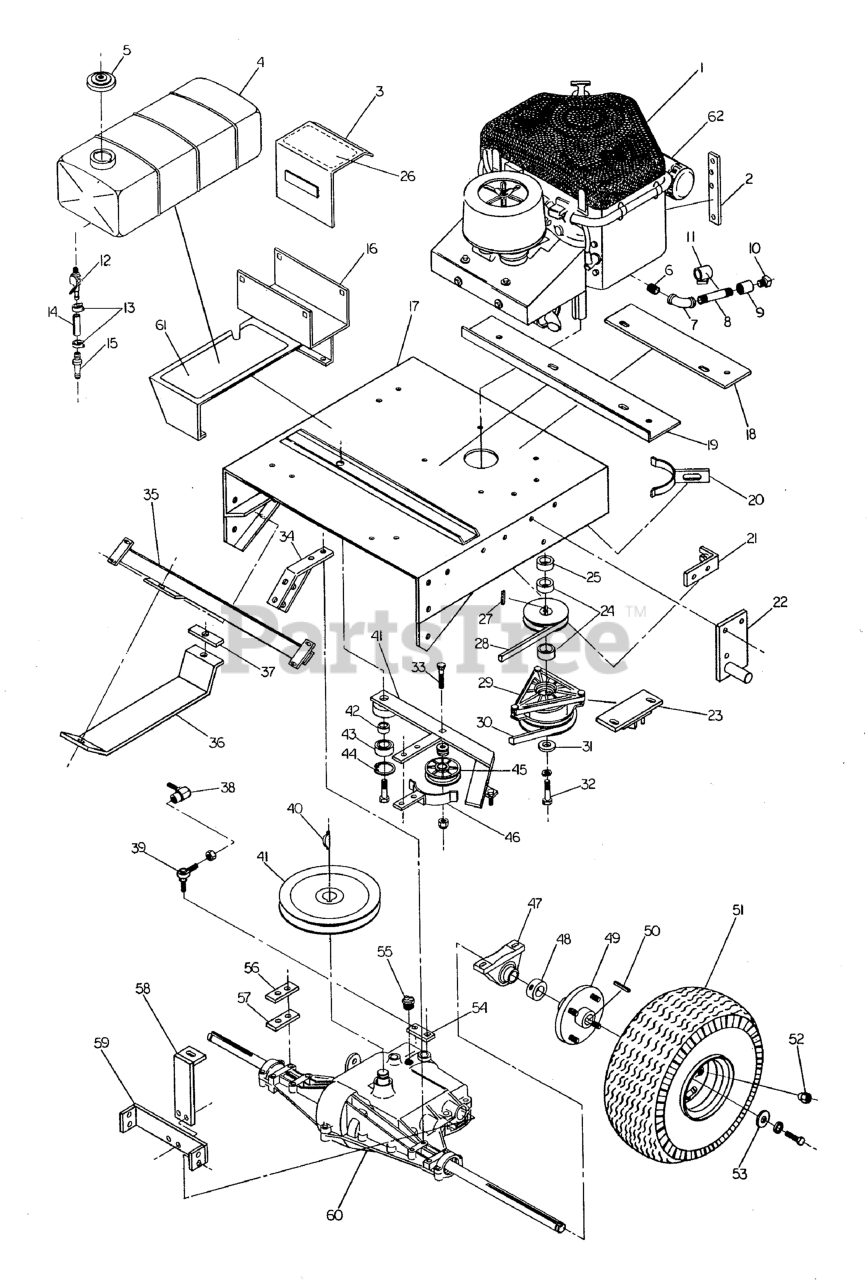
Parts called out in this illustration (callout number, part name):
2	Oil Filter Mount
3	Battery Cover
4	Fuel Tank, 4 Gallon
4	Gas Tank Strap
5	Gas Cap
6	Close Nipple
7	Elbow 45 Degree
8	Pipe Nipple
9	Coupler
10	Pipe Plug
11	Oil Drain Hold Down
12	Fuel Shut-Off Valve
13	CLAMP, Hose
14	Fuel Line
15	FUEL FILTER
16	Gas Tank Mount
17	Engine Deck
18	Rear Engine Deck Support
19	Front Engine Deck Support
20	Engine Belt Guide
21	Clutch Cable Bracket
22	Pivot Bracket - LH
22	Pivot Bracket - RH
23	Electric Clutch Anchor
24	SPACER, 1.01 x 1.50 x .37
25	Transaxle Pulley
26	SAFETY WALK
27	KEY, 1/4" SQ. X 1-1/4
28	Belt Ground Drive
29	CLUTCH, Electric, 1" Shaft
30	BELT, B-Section
30	Belt 48" Deck
31	SPACER, .45 x 1.62 x .37
34	Torque Arm
35	Engine Deck Cross Member
36	Skid Plate
37	Skid Plate Spacer
38	BALL JOINT, 3/8" Female Studded
39	BALL JOINT, 3/8-24 Male, Studded
40	Hy Pro Key
41	Ground Drive Pulley
42	INSERT, Bearing Shoulder
43	BEARING, BALL 11/16X1-9/16X15/32
44	SNAP RING, Internal
45	Idler Pulley
46	Belt Guide
47	BEARING, PILLOW BLOCK, 1
48	COLLAR, 1" Split
49	4-Bolt Hub
50	KEY, 1/4 SQ. X 2-1/2
51	WHEEL & TIRE ASSEMBLY, 20 x 10 x 8, Complete
51	TIRE & WHEEL ASSEMBLY, 18 X 8.5 X 8
52	LUG NUT, 1/2-20
53	Retaining Spacer
54	Shifting Lever
55	Neutral Safety Switch
56	3/16 Transmission Spacer
57	1/4 Transmission Spacer
58	Transmission Support Arm
59	Transmission Support Bracket
60	6 Speed Transaxle
61	Gas Tank Safety Walk
62	AIR FILTER (45 083 02)
